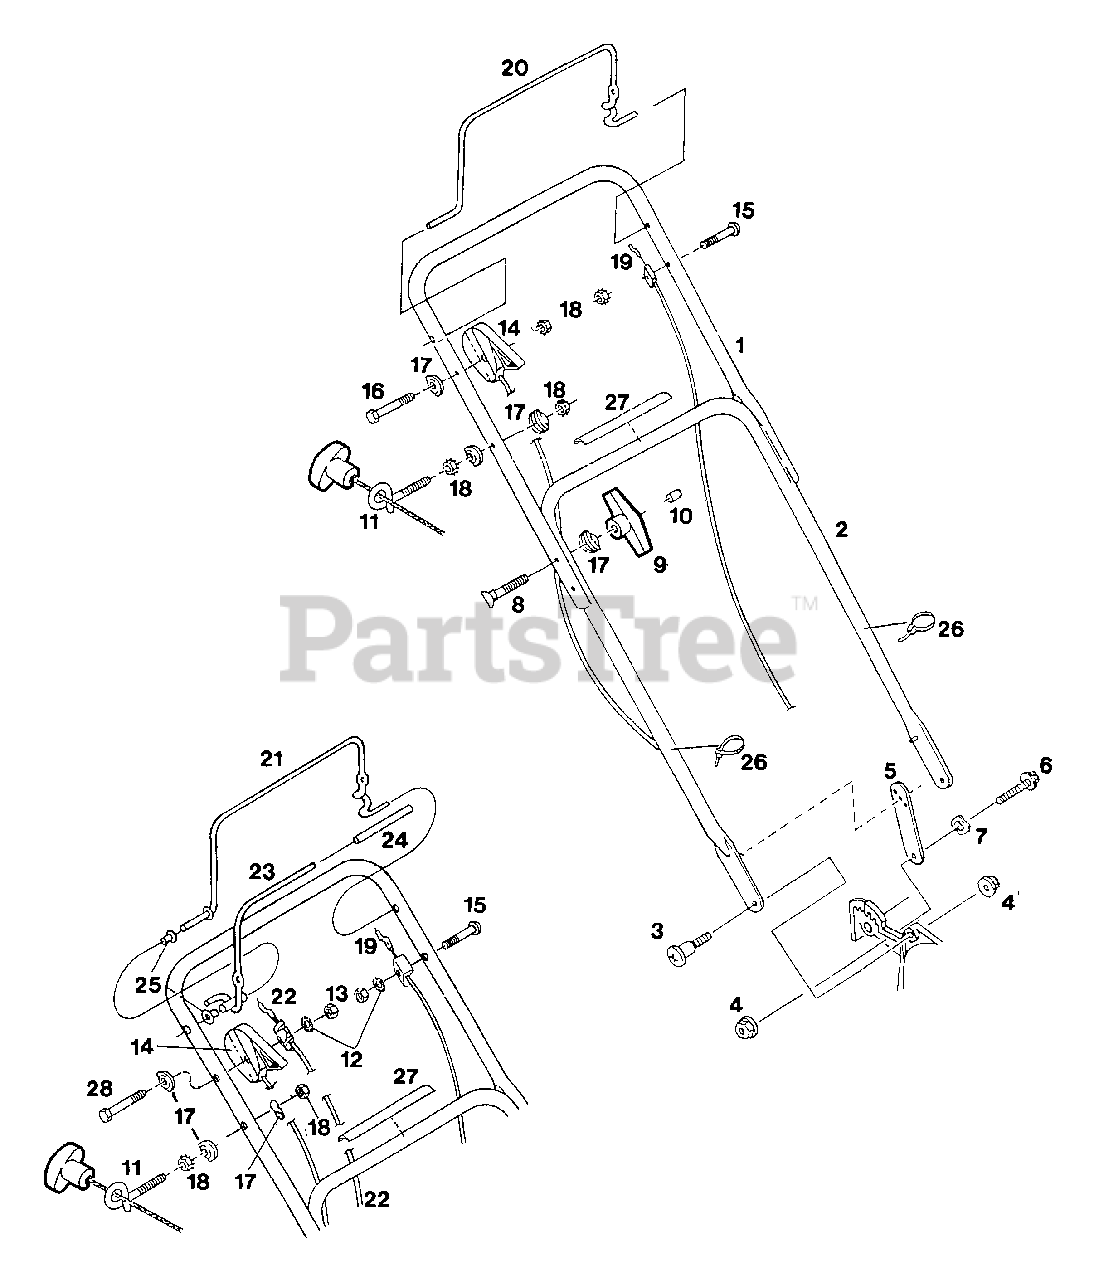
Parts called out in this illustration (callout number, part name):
1	Handle - upper
2	Handle - lower
3	Bolt - handle 5/16-18
4	Nut - hex 5/16-18 flng lock
5	Plate - handle adjust
6	Bolt - handle support 5/16-18
7	Washer - wave 5/16
8	Bolt - crvd Ld 5/16-18 x 2-1/4
9	Knob - handle, plastic
10	Cap - bolt end
11	Eyebolt-starter rope 1/4-20
12	Washer - ext tooth 1/4
13	Nut - hex 1/4-20
14	Control - throttle w/cable
16	Screw - truss hd 1/4-20 x 1-3/4
17	Washer - curved
18	Nut - hex 1/4-20 Keps
19	Cable - engine/blade control
20	Bail - engine/blade control
21	Bail - engine/blade control
22	Cable - traction drive
23	Bail - traction drive
24	Sleeve - drive bail
25	Bushing - drive bail
26	Cable Tie
27	Decal - starting instructions
28	Bolt - hex 1/4-20 x 2 1/2
